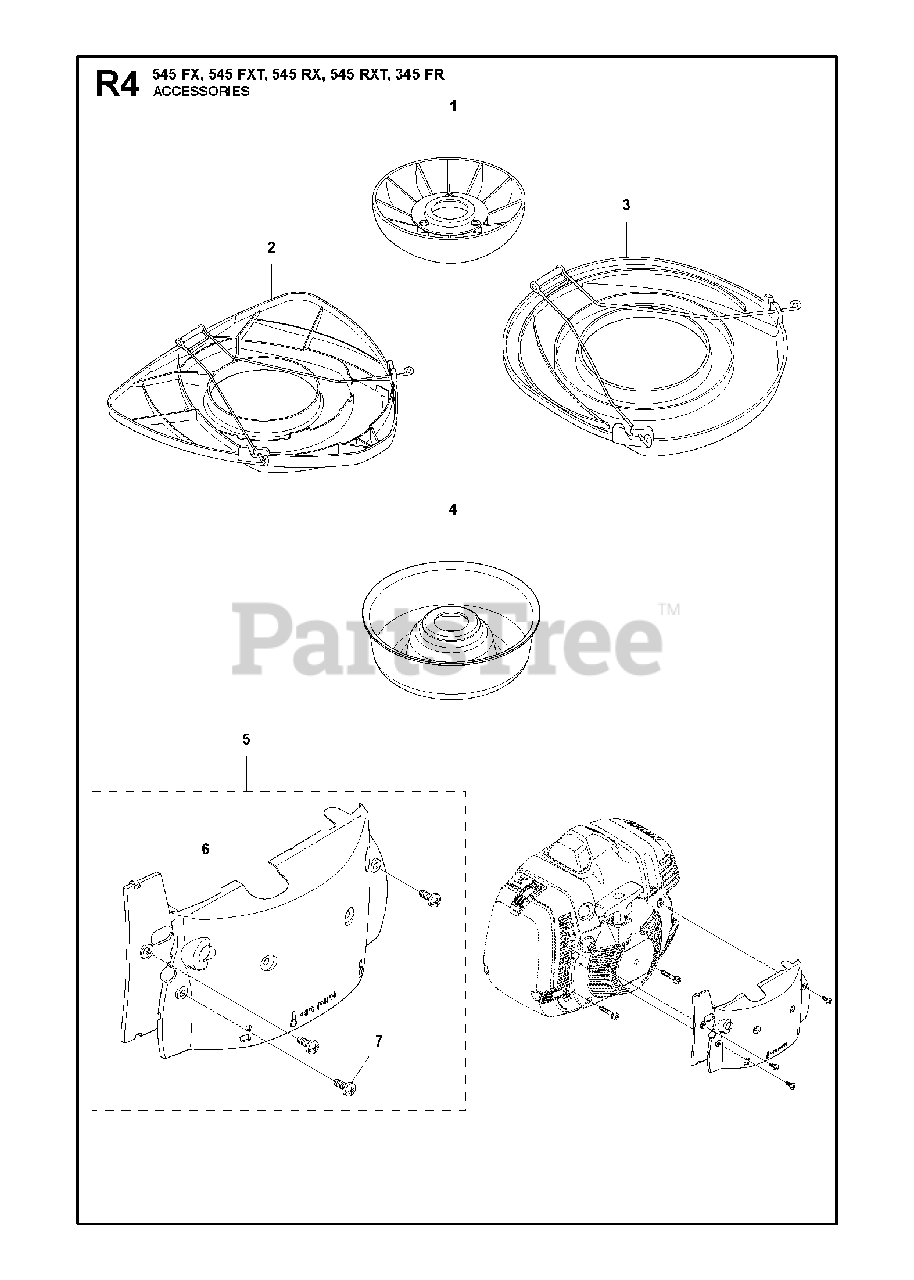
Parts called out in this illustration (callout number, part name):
1	SUPPORTING CUP
2	TRANSPORT GUARD
3	BLADE GUARD TRANSPORT
4	SUPPORT CUP
5	WINTER KIT
6	WINTER COVER
7	SCREW
